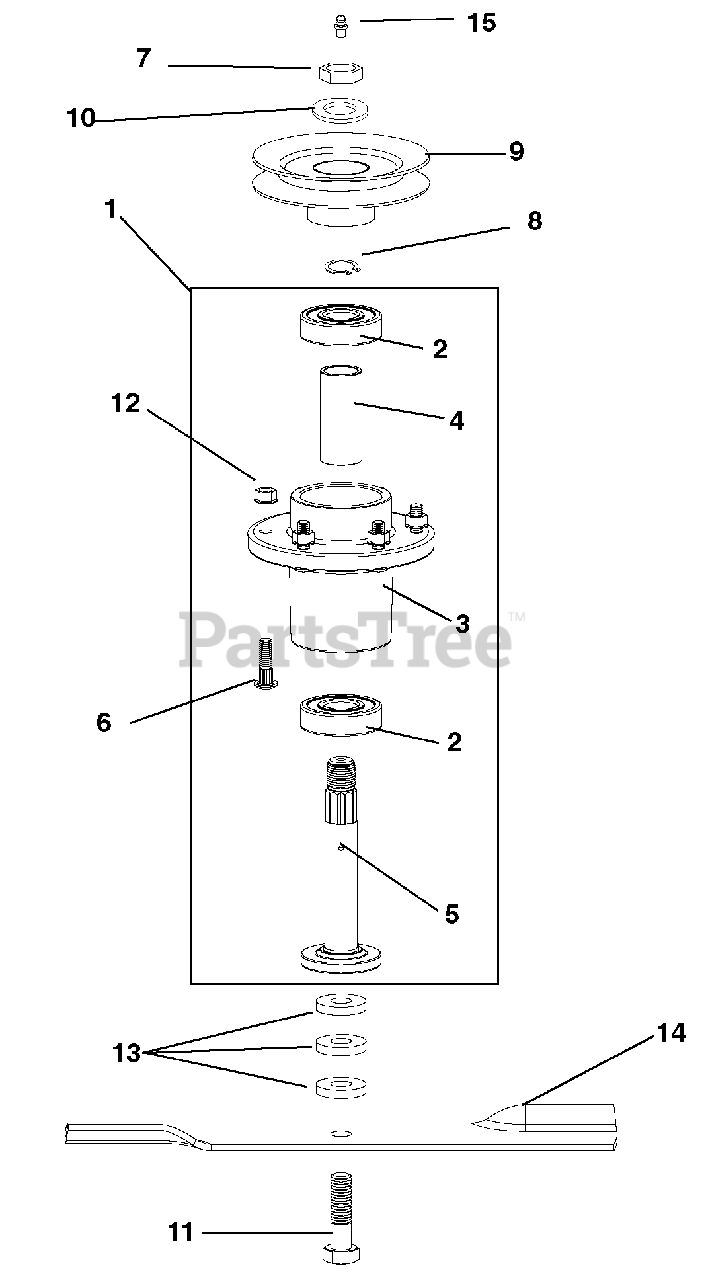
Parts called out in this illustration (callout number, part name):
1	Spindle Assembly (Includes 2, 3, 4, 5, & 15)
2	Bearing, 6305LLC
3	Casting, Spindle W/STUDS
4	Spacer, 1.250 x 1.000 x 2.780
5	Shaft, Spindle .75-16
6	Bolt, .38-16 x 1.25 Round Head Square Neck
7	Nut, 3/4-16 Crown Lock
8	Ring, Retainer
9	Pulley, Cutter Housing - Refer to Deck Assembly on page 24 or page 26
10	Washer, .75 x 1.312 x .120
11	Bolt, 5/8-11 x 2.00 Hex 8
12	Nut, .38-16 Standard Hex Grade 5
13	Washer, .630 x 1.50 x .250 Flat
14	Blade, 16.500 x .80 Lift (48-Inch Decks)
15	Zerk, Grease S/O
